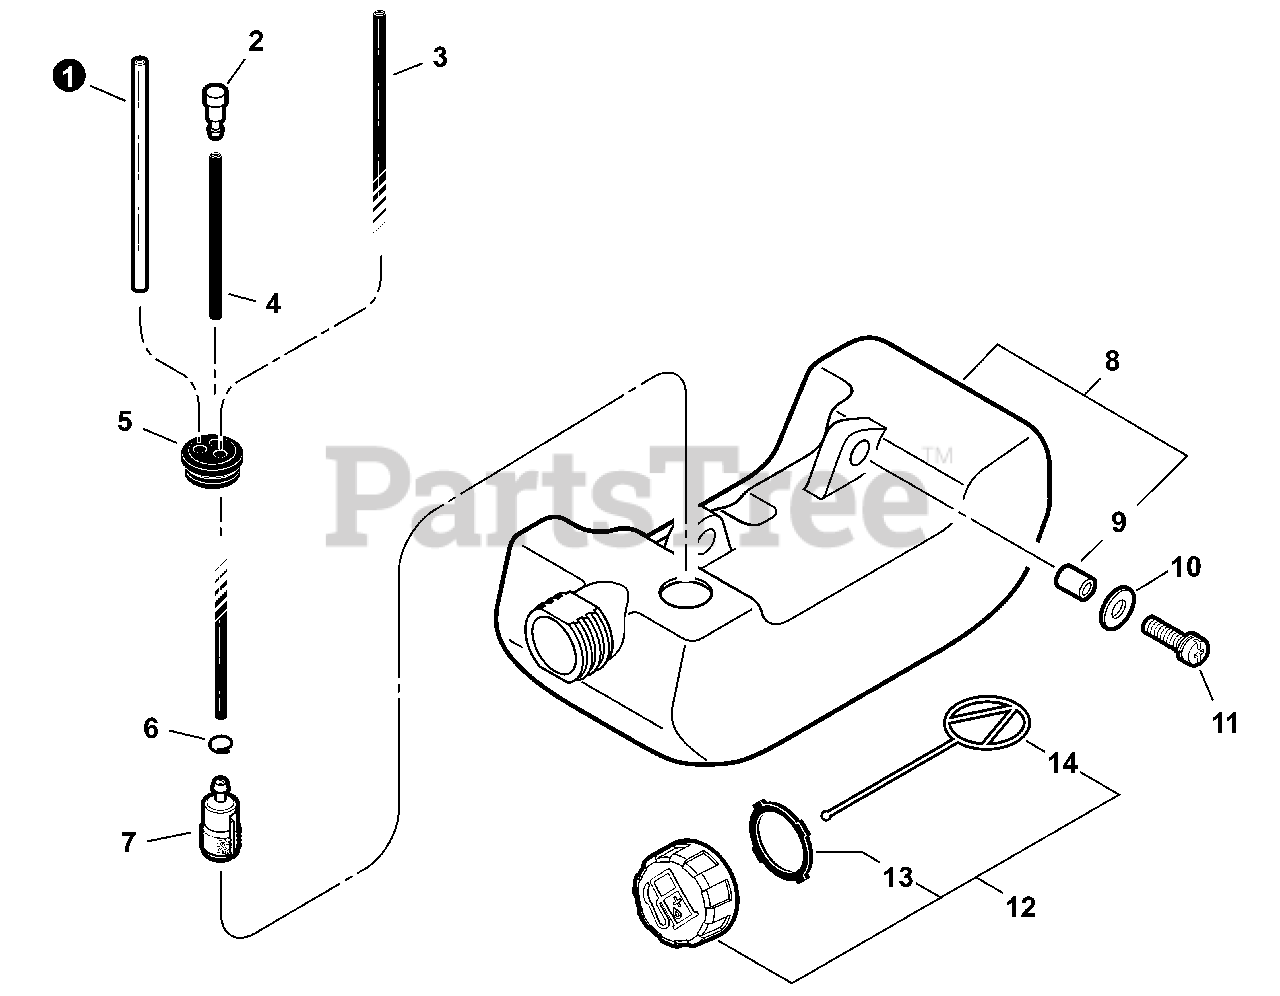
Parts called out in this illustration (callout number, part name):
1	PIPE, FUEL RETURN 3×6×90 MM
2	VENT ASSY
3	PIPE, FUEL 3×5×180
4	PIPE, FUEL 3×5×70 BLACK
5	GROMMET, FUEL
6	CLIP 6 MM
7	FILTER, FUEL
8	TANK, FUEL
9	SPACER 6.2×7.8×6
10	WASHER 5.5×12×0.8
11	BOLT 5×16
12	CAP ASSY, FUEL
13	GASKET, FUEL CAP
14	CONNECTOR, CAP L= 100 MM
